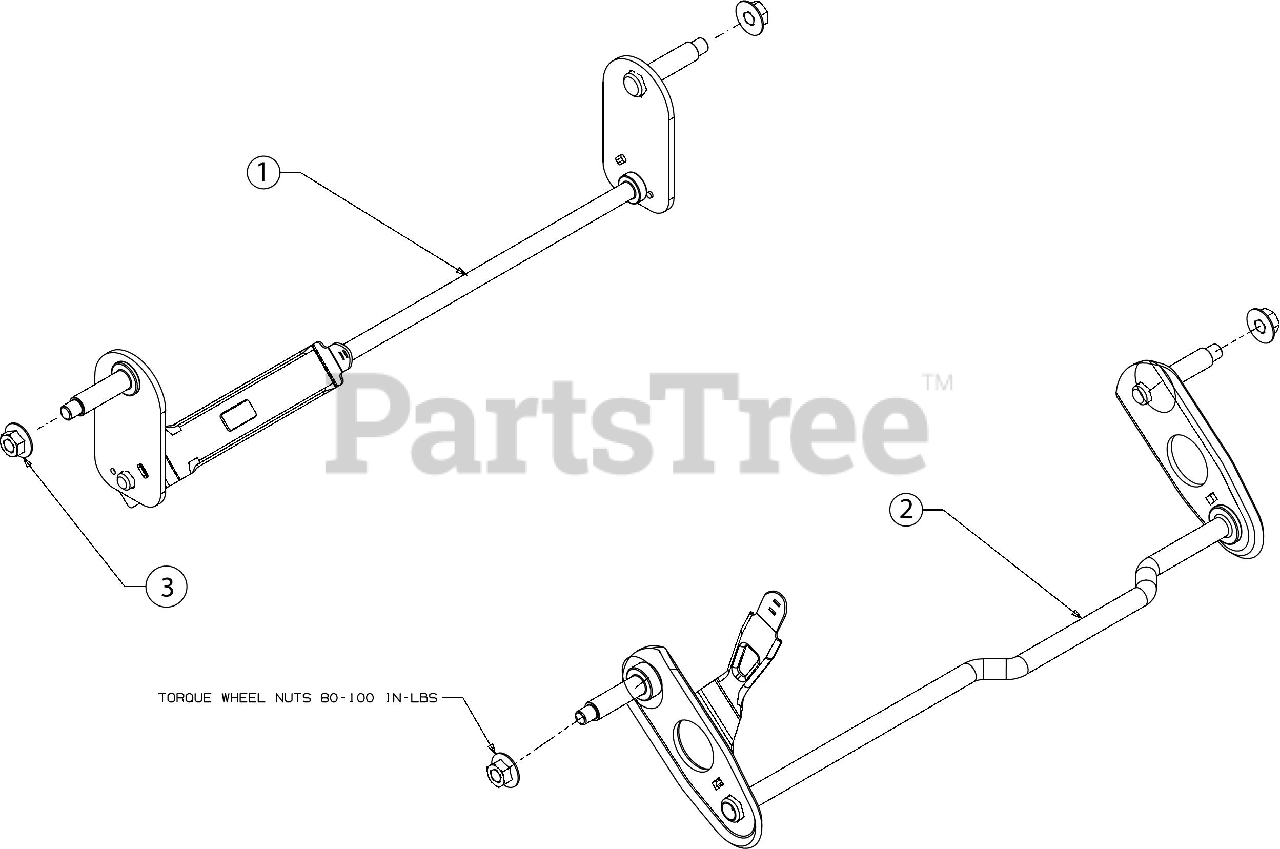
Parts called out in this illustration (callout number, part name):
1	REAR AXLE ASSEMBLY
2	8" FRONT AXLE ASSEMBLY
3	FLANGE LOCK NUT
